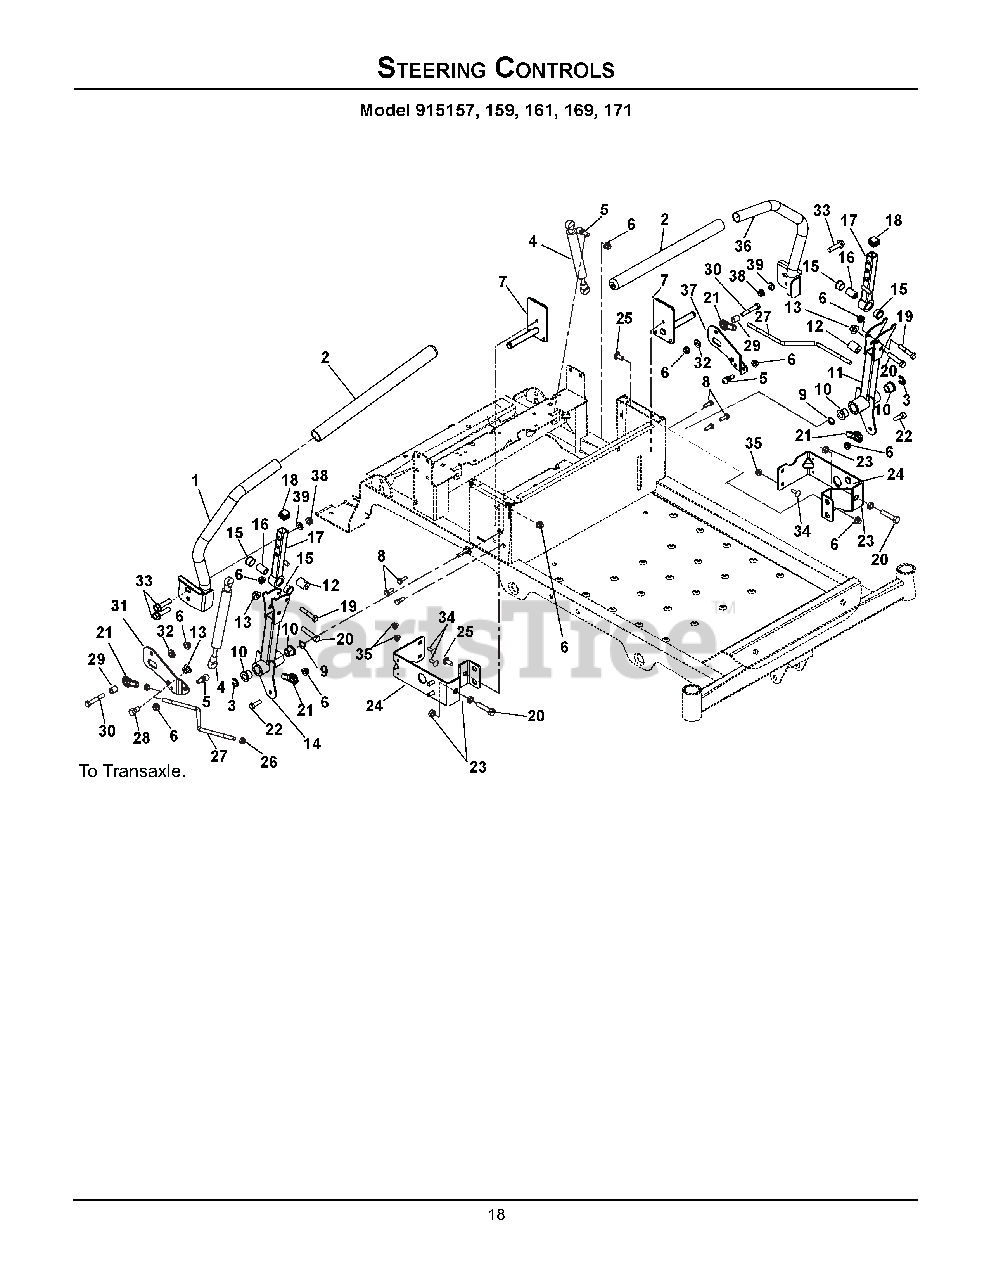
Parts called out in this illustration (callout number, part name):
1	WMT, STEERING HANDLE
2	GRIP, HANDLEBAR 15" FOAM
3	RG-RTNG-EXT .500X.042 (E)
4	DAMPER, STABILUS
5	STUD- BALL
6	@NUT-LK-NYL-FLG .31-18 YWZC
7	WMT, STEERING SHAFT
8	SCR-TAP .25-20X.50 HWH TR YWZ
9	WSHR-WAVE .50X.75X.015 .13FRHT
10	BSHG-FLG .500X.750X.625X.937
11	WMT, LOWER CONTROL ARM
12	BSHG, ECCENTRIC .328X.750X.970
13	@NUT-LK-NYL-FLG .38-16 YWZC
14	WMT, LOWER CONTROL RH
15	BSHG-FLG, .625X.75X.450X.875
16	SPACER, .375X.625X.970 (PM)
17	WMT, UPPER CONTROL ARM
18	CAP PLUG, SQ 3/4-14-20 RIBBED
19	@BLT-HEX .31-18X1.75 GR5 YWZC
20	BLT-HEX .375-16X1.750 FTD YWZC
21	ALIGNABALL, 5/16 RH THREAD
22	@BLT-HEX .31-18X1.00 GR5 YWZC
23	NUT-HEX-JAM .375-16 YWZC
24	WMT, STEERING STOP
25	@BLT-RHDSSQNK .31-18X.75 G5YZ
26	NUT-JAM .31-24 YWZC
27	WIREFORM, STEERING LINK
28	@BLT-HEX .38-16X.75 GR5 YWZC
29	SPACER, .328X.500X.625
30	@BLT-HEX .31-18X2.00 GR5 YWZC
31	PLATE, DAMPER RH
32	BSHG-FLG .316X.430X.225X.750
33	BLT-SERHFWH .375-16X1.25 YWZC
34	@BLT-RDHDSQNK .25-20X.75 G5YZ
35	@NUT-LK-NYL-FLG .25-20 YWZC
36	WMT, STEERING HANDLE LH
37	PLATE, DAMPER (LH)
38	@NUT-LK-CTR-JAM .375-16 YWZC
39	@WSHR-FL-STL.406X.812X.065 YWZ
